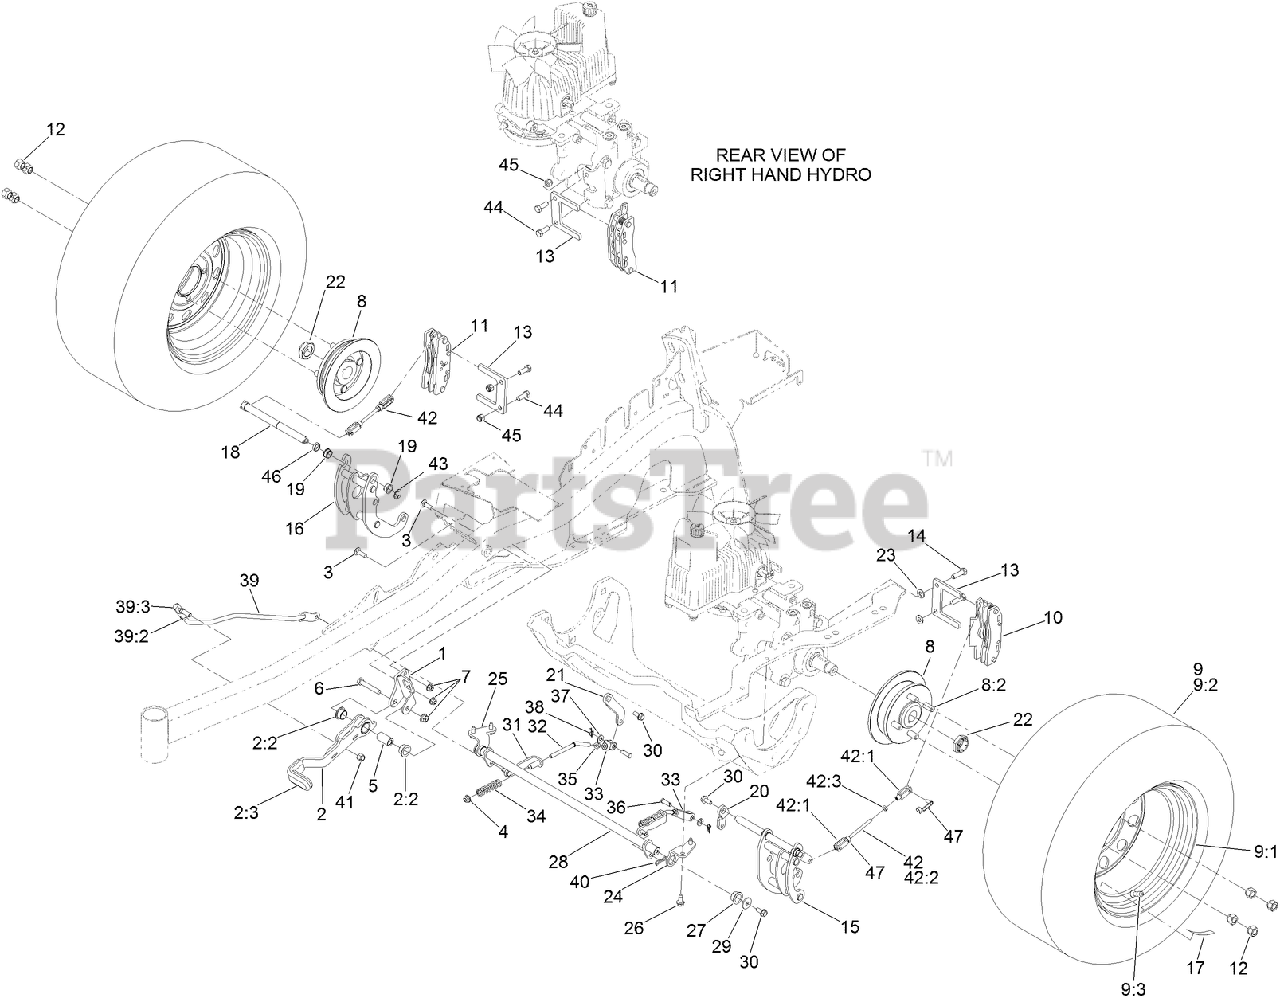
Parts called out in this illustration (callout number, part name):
1	BRACKET-MOUNT
2	BRAKE LEVER ASM
2:2	BUSHING-FLANGE
2:3	GRIP-LEVER
3	BOLT-CARR
4	NUT-HF, NI
5	HANDLE-PIVOT, BRAKE
6	SCREW-HH
7	NUT-HF, NI
8	WHEEL HUB ASM
8:2	STUD-WHEEL
9	WHEEL AND TIRE ASM
9:2	TIRE
9:3	STEM-VALVE
10	CALIPER-BRAKE
11	CALIPER-BRAKE, RH
12	NUT-LUG
13	PLATE-MOUNT, BRAKE
14	SCREW-LOCK, PATCH
15	MOUNT-BELLCRANK, LH
16	MOUNT-BELLCRANK, RH
17	DECAL-TORQUE, WHEEL HUB LUG
18	BELLCRANK
19	BUSHING
20	ARM-INNER, LH
21	ARM-INNER, RH
22	LOCKNUT
23	WASHER-FLAT
24	MOUNT-PIVOT, LH
25	MOUNT-PIVOT, RH
26	SCREW-HWHTF
27	BUSHING-FLANGE
28	SHAFT-CROSS
29	WASHER-FLAT
30	SCREW
31	BRACKET-L
32	LINKAGE-MID
33	YOKE-OFFSET
34	SPRING-COMPRESSION
35	NUT-JAM
36	PIN-CLEVIS
37	WASHER-PLAIN
38	PIN-COTTER, LOCKING
39	FRONT LINKAGE ASM
39:2	END-TIE ROD, RH
39:3	NUT-HJ
40	PIN-COTTER, LOCKING
41	NUT-LOCK
42	REAR LINKAGE ASM
42:1	YOKE
42:2	LINKAGE, REAR
42:3	NUT-JAM
43	E-RING
44	SCREW-HH
45	NUT-LOCK, NI
46	SPACER
47	PIN-CLEVIS, SPRING
